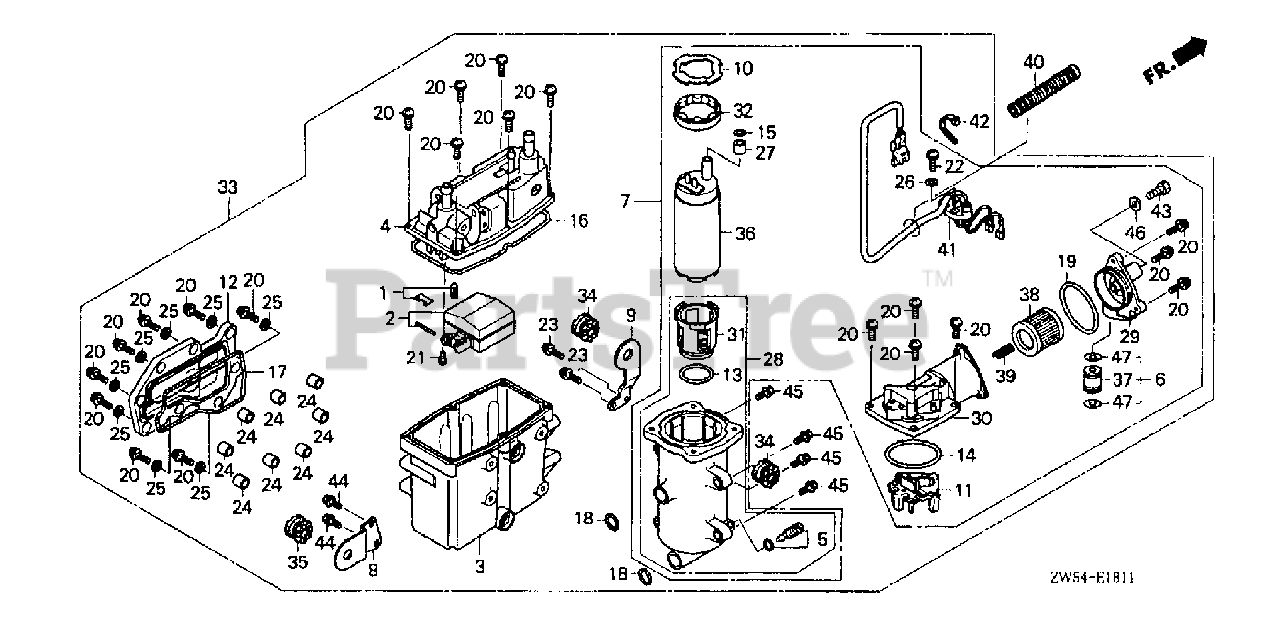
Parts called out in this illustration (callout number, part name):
1	VALVE SET, FLOAT
2	FLOAT SET
3	BODY, CHAMBER
4	COVER
5	SCREW SET, DRAIN
6	JOINT SET
7	PUMP UNIT SET A, FUEL
8	STAY, PLATE (A)
9	STAY, PLATE (B)
10	PLATE
11	HOLDER
12	COVER, WATER JACKET
13	O-RING
14	O-RING
15	O-RING
16	O-RING
17	O-RING
18	O-RING
19	O-RING
20	SCREW-WASHER
21	SCREW, PAN
22	SCREW, WASHER
23	SCREW, WASHER
24	COLLAR
25	WASHER, PLAIN
26	WASHER, PLAIN
27	COLLAR
28	CASE, PUMP
29	COVER B, PUMP
30	COVER, PUMP (A)
31	INSULATOR
32	INSULATOR
33	SEPARATOR ASSY., VAPOR
34	GROMMET, VAPOR SEPARATOR
35	GROMMET, VAPOR SEPARATOR
36	PUMP UNIT, FUEL
37	JOINT, FUEL PIPE
38	SCREEN, FUEL STRAINER
39	SPRING, SET
40	TUBE, CORRUGATE (7MM)
41	HARNESS
42	BAND
43	BOLT, SEALING (6MM)
44	BOLT, FLANGE (6X16)
45	BOLT, FLANGE (6X25)
46	WASHER, SEALING (6MM)
47	O-RING (7.8X1.9) (ARAI)
